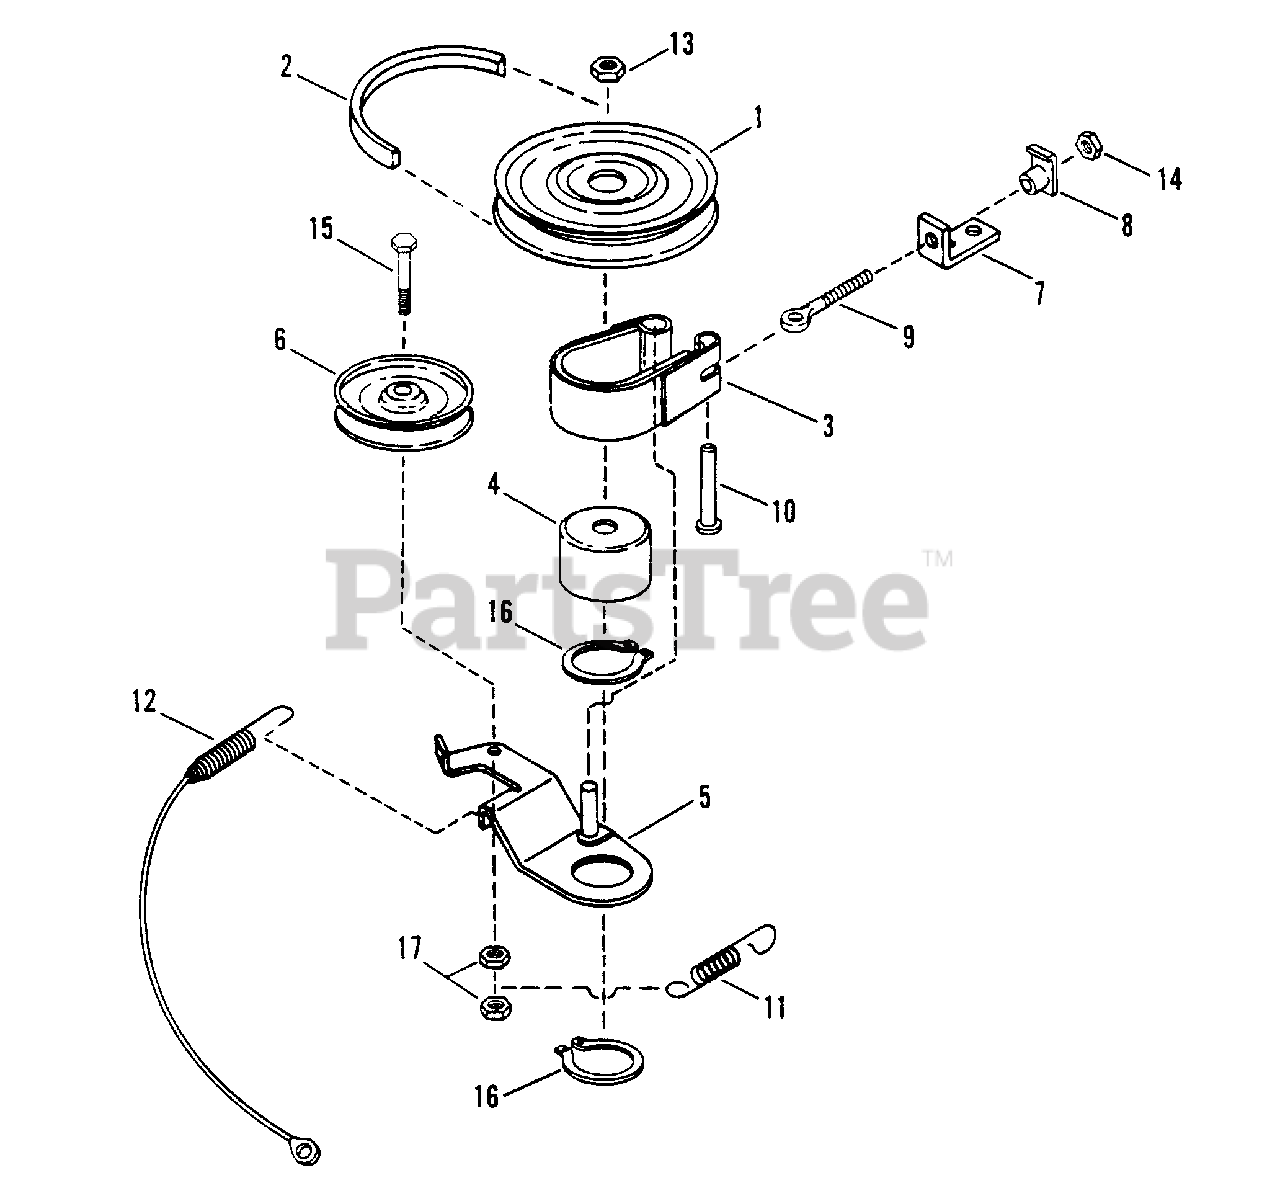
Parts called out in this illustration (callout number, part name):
1	PULLEY, Drive 5.75" OD
2	BELT, Drive A101
3	ASSEMBLY, Brake Band
4	DRUM, Brake
5	ASSEMBLY, Brake Arm
6	PULLEY, Flat Idler 4.12" OD
7	ANCHOR, Brake
8	TEE-NUT, 1/4-20
9	BOLT, 1/4-20 Eye
10	PIN, 1/4 x 1 1/4" Clevis
11	SPRING, Blade Brake
12	CABLE, Blade 30.44"
13	NUT, 3/4-16 Hex Jam
14	NUT, 1/4-20 Hex
15	SCREW, 3/8-24 x 2" Hex Head Cap
16	RING, 2" External Retaining
17	NUT, 3/8-24 Hex Lock
